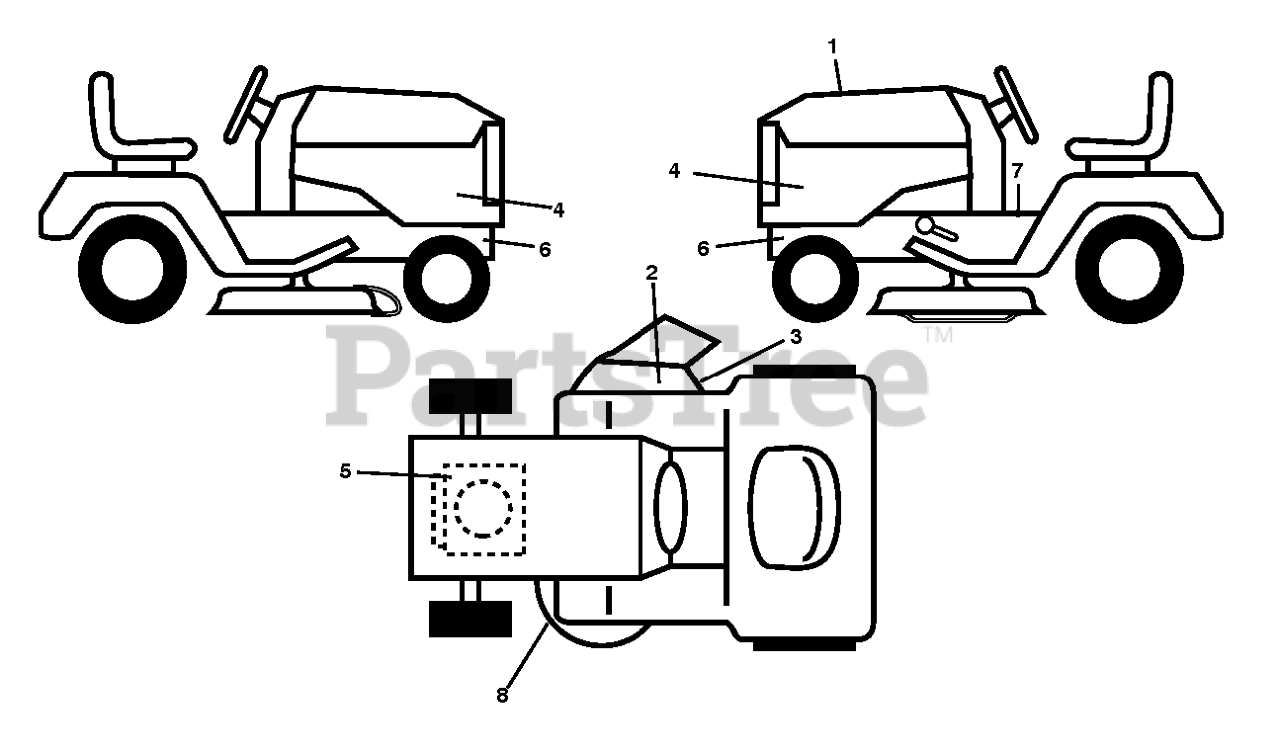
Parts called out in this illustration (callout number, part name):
2	DECAL.DECK.DEFLECTOR.WARNING
2	DECAL, DECK DEFLECTOR, WARNING
3	DECAL.DFLCTR.WARNNG.CTFNGR.SYM
5	DECAL.ENGINE.WARNING
6	DECAL.CHASSIS.HOT.MUFFLER
7	DECAL.TRACTOR.SADDLE
8	DECAL.DECK.BELT.ROUTE.42"2021
8	DECAL.V-BELT.SCH.42/46"MEC/ELE
